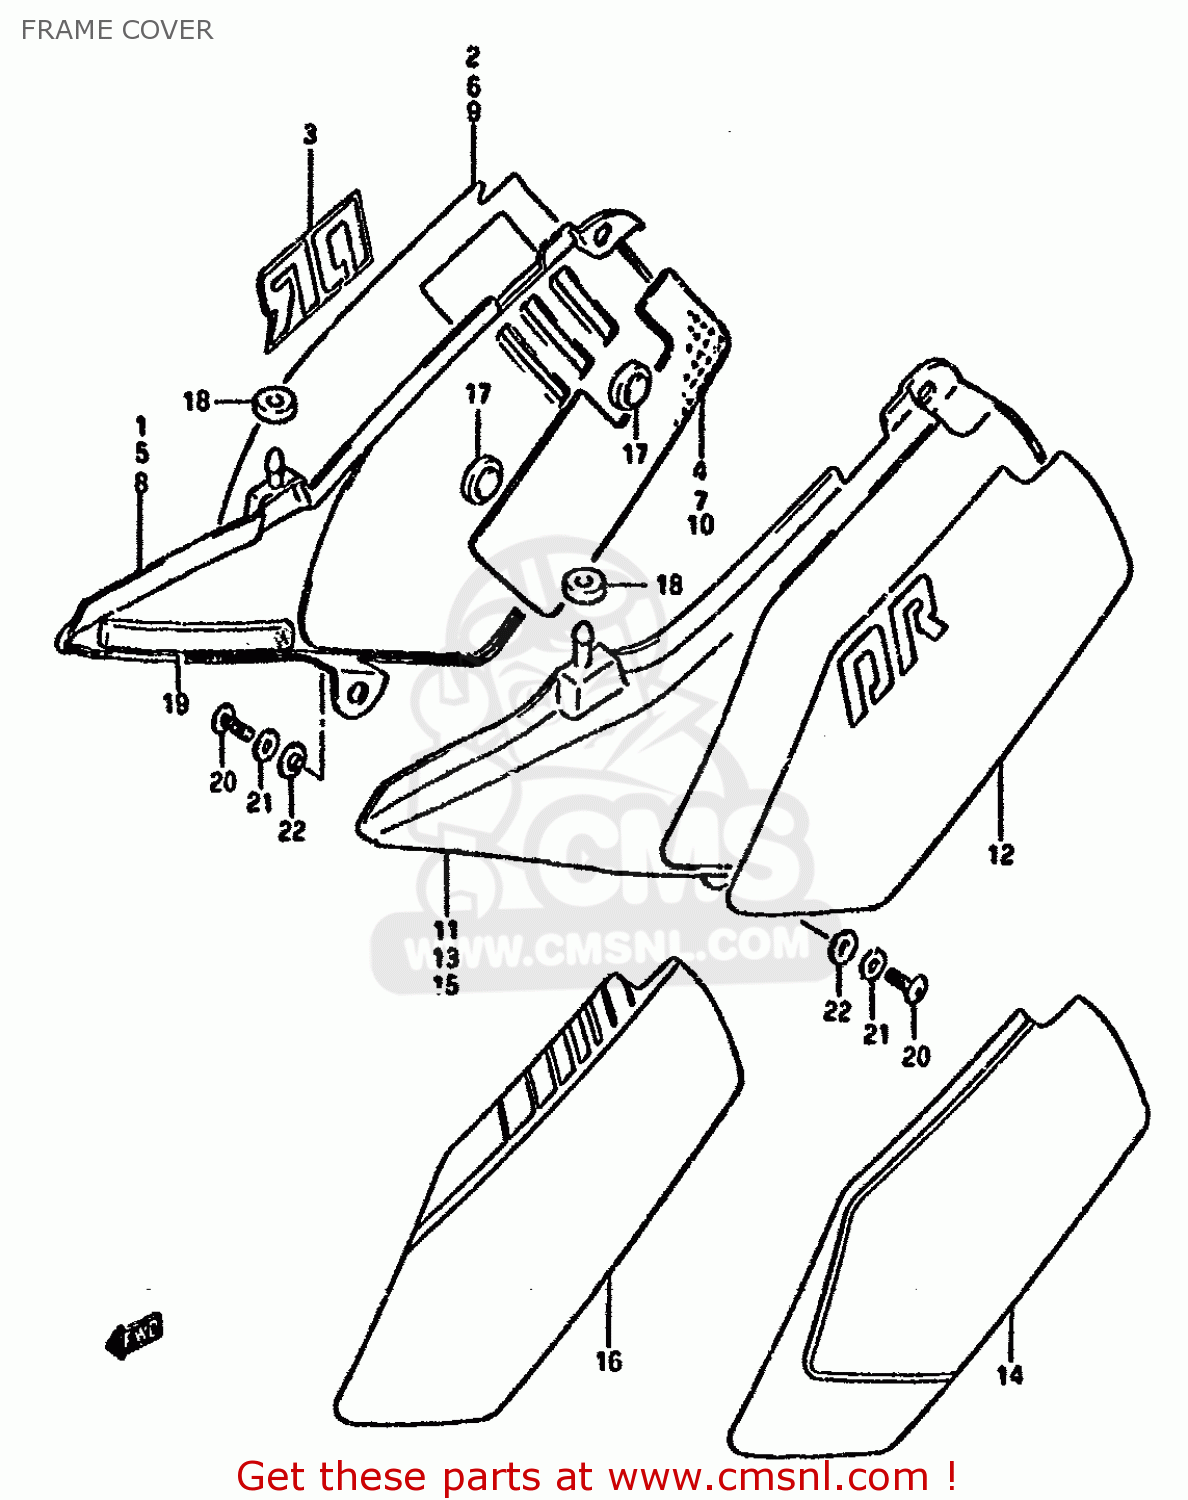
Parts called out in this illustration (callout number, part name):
1	COVER,FRAME,RIGHT
2	TAPE SET,FRAME COVER RH
3	EMBLEM
4	SHIELD,FRAME COVER,RIGHT
5	COVER,FRAME RH (BLUE)
6	TAPE SET,FRAME COVER RH
7	SHIELD,FRAME COVER,RIGHT
8	COVER,FRAME,R(BLUE)
9	TAPE,FRAME COVER RH
10	SHIELD,FRAME COVER,RIGHT
11	COVER,FRAME,LEFT
12	TAPE SET,FRAME COVER LH
13	COVER,FRAME LH (BLUE)
14	TAPE SET,FRAME COVER LH
15	COVER,FRAME,L(BLUE)
16	TAPE,FRAME COVER LH
17	CUSHION
18	CUSHION,SIDE COVER BOSS
19	CUSHION,FRAME COVER
20	SCREW
21	WASHER (6.5X18X1.6)
22	WASHER
